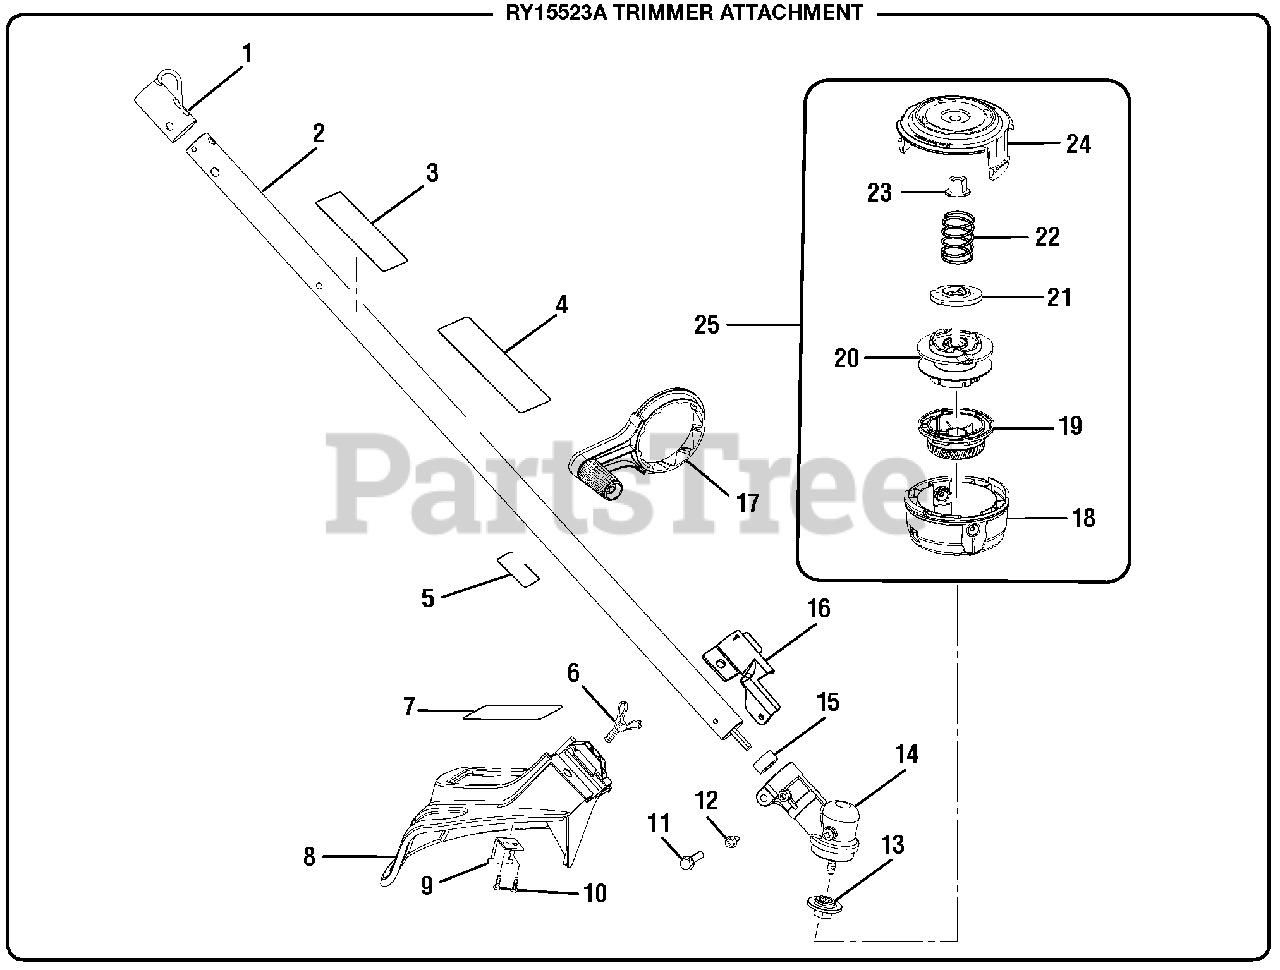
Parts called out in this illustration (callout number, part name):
1	Hanger Cap
2	Straight Shaft Assembly
3	Warning Icon Label
4	Ryobi EXPAND-IT Label
5	Data Label
6	Wing Screw (1/4-20 x 3/4 in.)
7	Logo Label
8	Grass Deflector Assembly
9	Line Cut-off Blade
11	Screw (1/4-20 x 1-1/4 in.)
12	Screw (10-24 x 5/8 in.)
13	FLANGED WASHER
14	Gear Head
16	Grass Deflector Clamp
17	Crank Handle Assembly
18	Lower Housing
19	Bump Knob (Green)
20	Spool Assembly
21	String Guide
23	Hex Flange Nut (M8, Left Hand)
24	Upper Housing
25	Stringhead Reel Assembly
